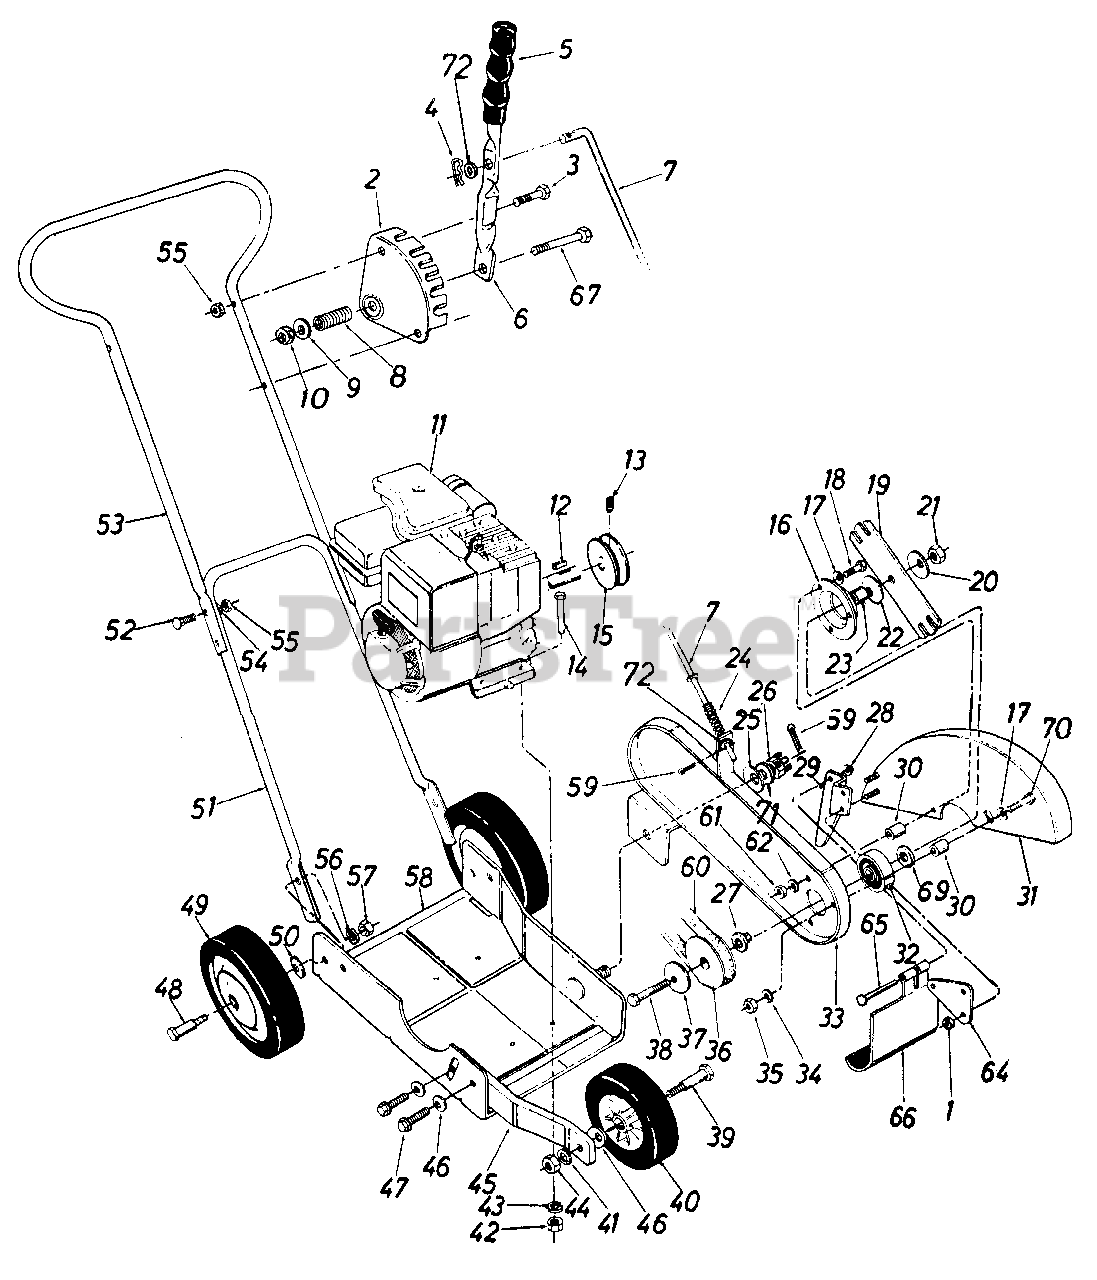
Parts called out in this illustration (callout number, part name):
1	Hex Cent. L.-Nut 1/4-20 Thd.
3	Hex Bolt 1/4-20 x 1.25" Lg.*
4	Cotter Pin 1/8" Dia. x 1.0" Lg. *
5	Grip
7	Clutch Rod
8	Compression Spring .50" O.D. x 1 38" Lg.
9	Fl.-Wash. 34" 1 D. x .62" O.D. .063
10	Hex Cent. L.-Nut 5/16-18 Thd.
11	Engine
12	Sq.Key 3/16 x 1.0" Lg.*
13	Set Scr. 1/4-28 x 1/4" Lg.
14	Hex Bolt 5/16-18 x 1.50' Lg.*
15	Engine Pulley
16	Bearing Housing
17	Bell.-Wash. .34" I.D. x 88" O.D. x .060
18	Hex Bolt 5/16-18 x 1.25" Lg.*
20	Bell.-Wash. .535" I.D. x 1.50" O.D. x.052
21	Hex Cent. L.-Nut 1/2-20 Thd.
22	Bell.-Wash. .535" I.D. x 1.50" O.D. x.052
23	Spacer
24	Compression Spring.57" O.D. x 1.92" Lg.
25	Bell.-Wash. .535" I.D. x 1.50" O.D. x.052
26	Hex Castle Nut 1/2-20 Thd.
27	Shoulder Spacer
28	Push Cap
29	Guide
30	Spacer .354" I.D. x .635" O.D. x .510" Lg.
33	Spindle Bracket Ass'y.
34	L.-Wash. 5/16" I.D.*
35	Hex Nut 5/16-18 Thd.
36	Pulley Half
37	Bell. Wash. .535" I.D. x 1.50" O.D. x.052
38	Hex Bolt 1/2-20 x 3.50" kJ.
39	Shoulder Bolt .498" Dia. x 1 .450
40	Wheel Ass'y. Comp. 6" Dia. x 1.50
41	L.-Wash. 3/8" I.D.*
42	Hex u t 5/16-18 Thd. *
43	L.-Wash. 5/16" I.L) .
44	Hex Nut 3/8-16 Thd.
45	Front Wheel Support
46	Bell.-Wash. .400" I.D. x 88" O.D. x .060
47	Hex Wash. Hd. Self Tap Scr. 3/8-16 x .75" Lg.
48	Shoulder Bolt. 498" Dia. x 1.150
49	Wheel Ass y. Comp. 7" Dia. x 1.50
50	Bell.-Wash. .400" I.D. x 88" 0. D .
51	L.ower Handle
52	Carriage Bolt 1/4-20 x 1.25" Lg. *
53	Upper Handle
54	L-. Wash. 1/4" 1.D.
55	Hex Nut 1/4-20 Thd.
56	L.-Wash. 3/8" I.D.*
57	Hex Nut 3/8-16 Thd.
58	Base Ass'y.
59	Cotter Pin 1/8" Dia. x 1.0" Lg. *
60	3V-Belt 31.2" Lg.
61	Hex Nut 5/16-18 Thd.*
62	L.-Wash. 5/16" I.D.*
64	Flap Bracket
65	Hinge Pin
66	Debris Deflector
67	Hex Bolt 5/16-18 x 1.75" Lg.
69	Fl.-Wash. .51 I.D. x 1.00 O.D. x.060
70	Hex Bolt 5/16-18 x 2.00" Lg.
71	Fl-Wash. 1/2" I.D.
72	Fl-Wash. 3/8" I.D.
